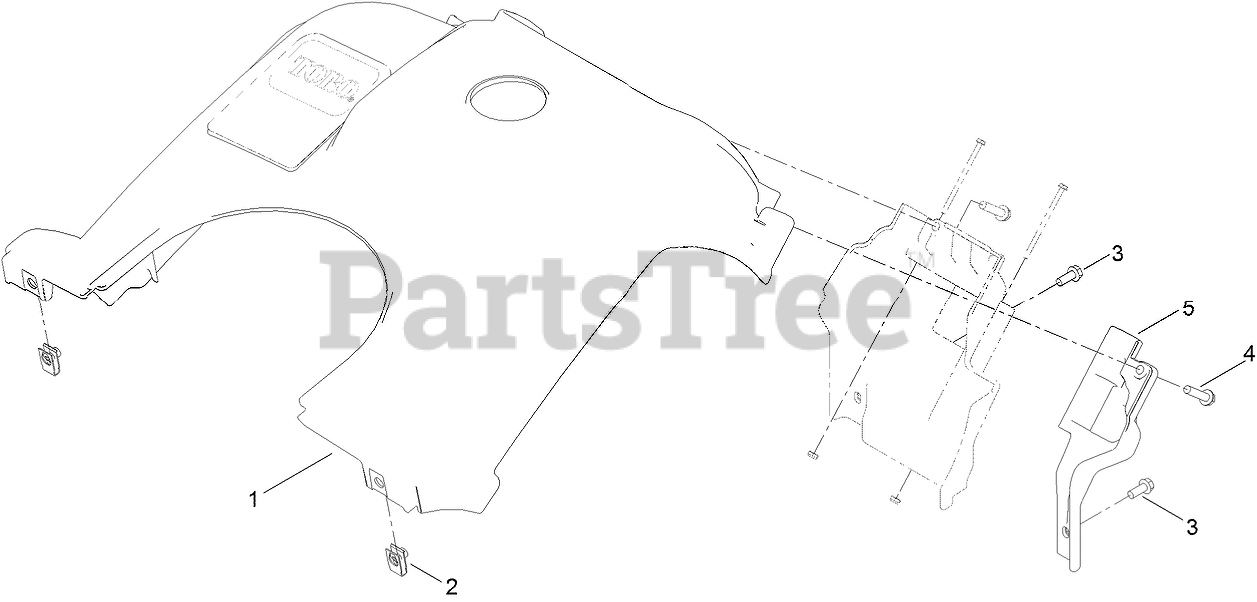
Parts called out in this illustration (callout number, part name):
1	SHROUD ASM
3	SCREW-HWH
4	SCREW-PLASTIC
5	SHROUD-LOWER, LH
